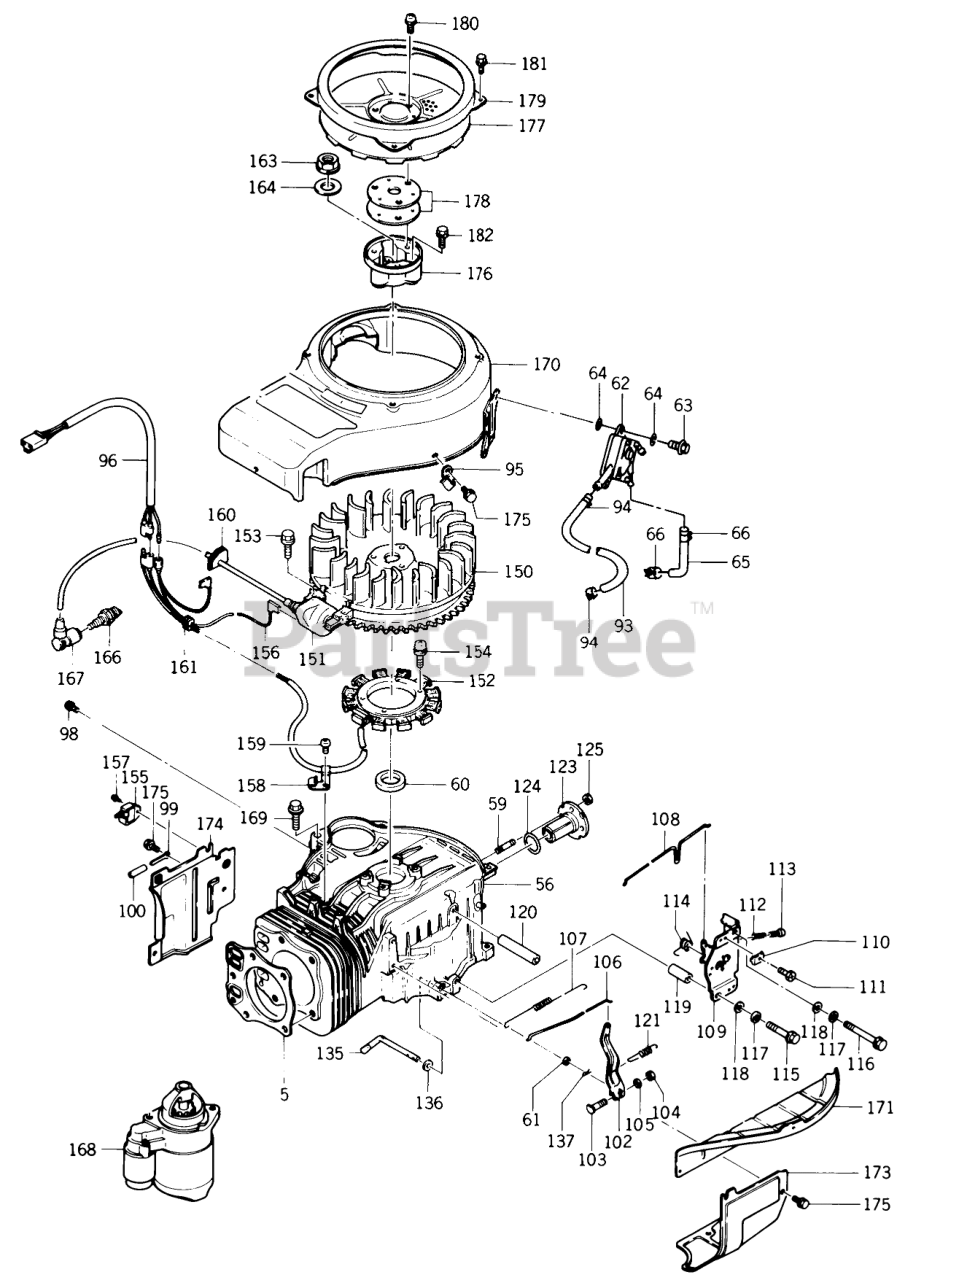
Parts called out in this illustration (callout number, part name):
5	GASKET HEAD
56	CASE-CRANK
60	SEAL OIL
61	SEAL-OIL, VC (6X10X2.5)
62	PUMP-FUEL ASSY
63	Bolt
64	WASHER
95	CLAMP
96	HARNESS
98	BOLT-FLANGED
99	CLAMP
102	ARM ASS'Y
103	Bolt
104	NUT 6MM
105	Washer
106	LINK GOVERNOR
107	SPRING-LINK
108	LINK CHOKE
109	PANEL-CONTROL
110	CLAMP
112	SPRING
113	SCREW PAN HEAD 4X25
114	SPRING
115	BOLT (6 X 50)
116	BOLT (6 X 90)
117	WASHER-SPRING 6MM
118	WASHER, CLUTCH
119	COLLAR
120	COLLAR
121	SPRING
123	SHAFT
124	O-RING
125	Nut
135	ARM-PIVOT
136	WASHER-PLAIN 6MM
137	Pin
150	FLYWHEEL ASS'Y
151	COIL IGNITION
152	COIL-CHARGING
154	SCREW (6 X 25)
155	IGNITER
156	LEAD WIRE
157	SCREW (4 X 8)
158	CLAMP
159	SCREW
160	GROMMET
161	GROMMET
164	WASHER
166	SPARK PLUG
167	CAP-SPARKPLUG
168	Starter Assembly See Section 10-7 For Complete Parts Breakdown
169	BOLT (8 X 35)
170	HOUSING-FAN
171	HOUSING-FAN
173	SHROUD
174	SHROUD
175	Bolt 6 x 12
176	BRACKET
177	SCREEN
179	GUARD
180	CLAMP
181	Bolt
182	BOLT (8 X 20)
